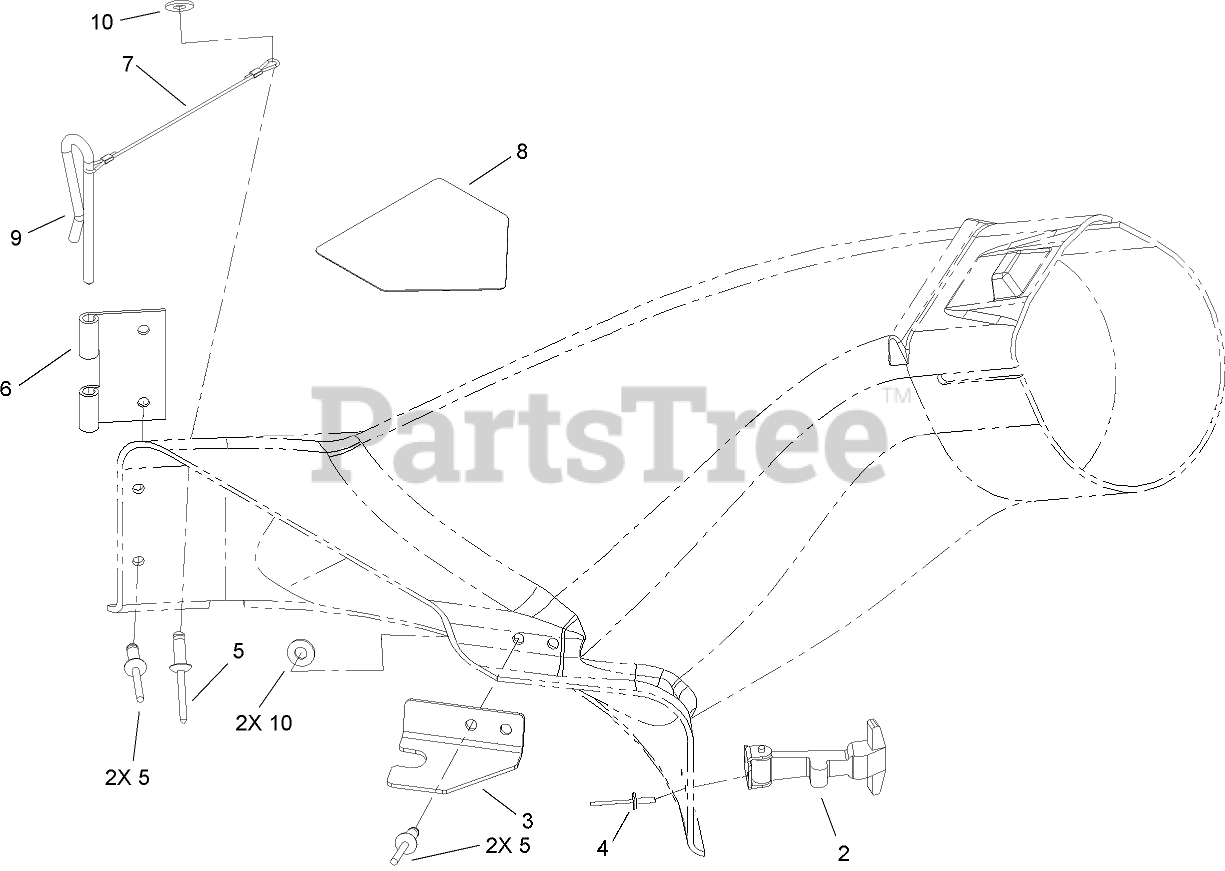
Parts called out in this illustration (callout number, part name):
2	HANDLE ASM
3	LATCH-ELBOW, BAGGER
4	RIVET-POP
5	RIVET-BLIND
6	BRACKET-MOUNTING, CHUTE
7	LANYARD
8	DECAL-DANGER, SHIELD
9	PIN-LOCKING, CHUTE
10	WASHER-FLAT
